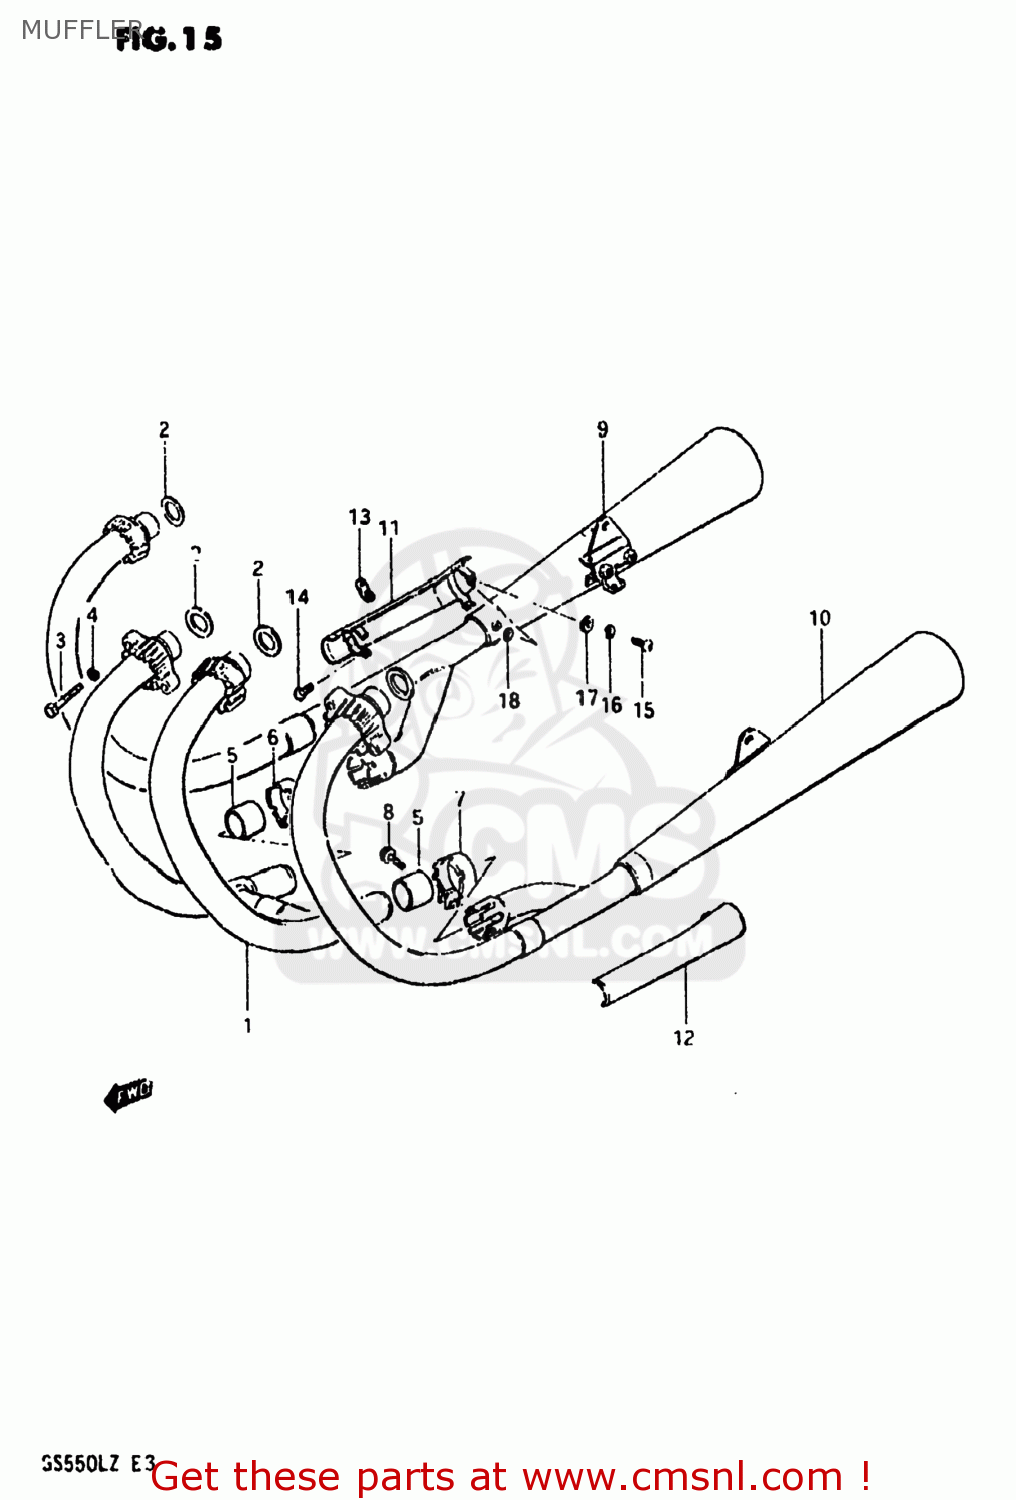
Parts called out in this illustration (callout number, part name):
1	PIPE,EXHAUST,CENTER
2	GASKET,EXHAUST PIPE (NAS)
3	BOLT
4	LOCK WASHER
5	CONNECTOR,MUFFLER
6	CLAMP,MUFFLER CONNECTOR,R
7	CLAMP,MUFFLER CONNECTOR,L
8	BOLT
9	MUFFLER ASSEMBLY
10	MUFFLER ASSEMBLY
11	COVER,MUFFLER
12	COVER,MUFFLER
13	CLAMP,MUFFLER COVER
14	SCREW 5X20
15	SCREW 6X12
16	LOCK WASHER
17	WASHER
18	GASKET 6.2X12X1.5 (MCA)
